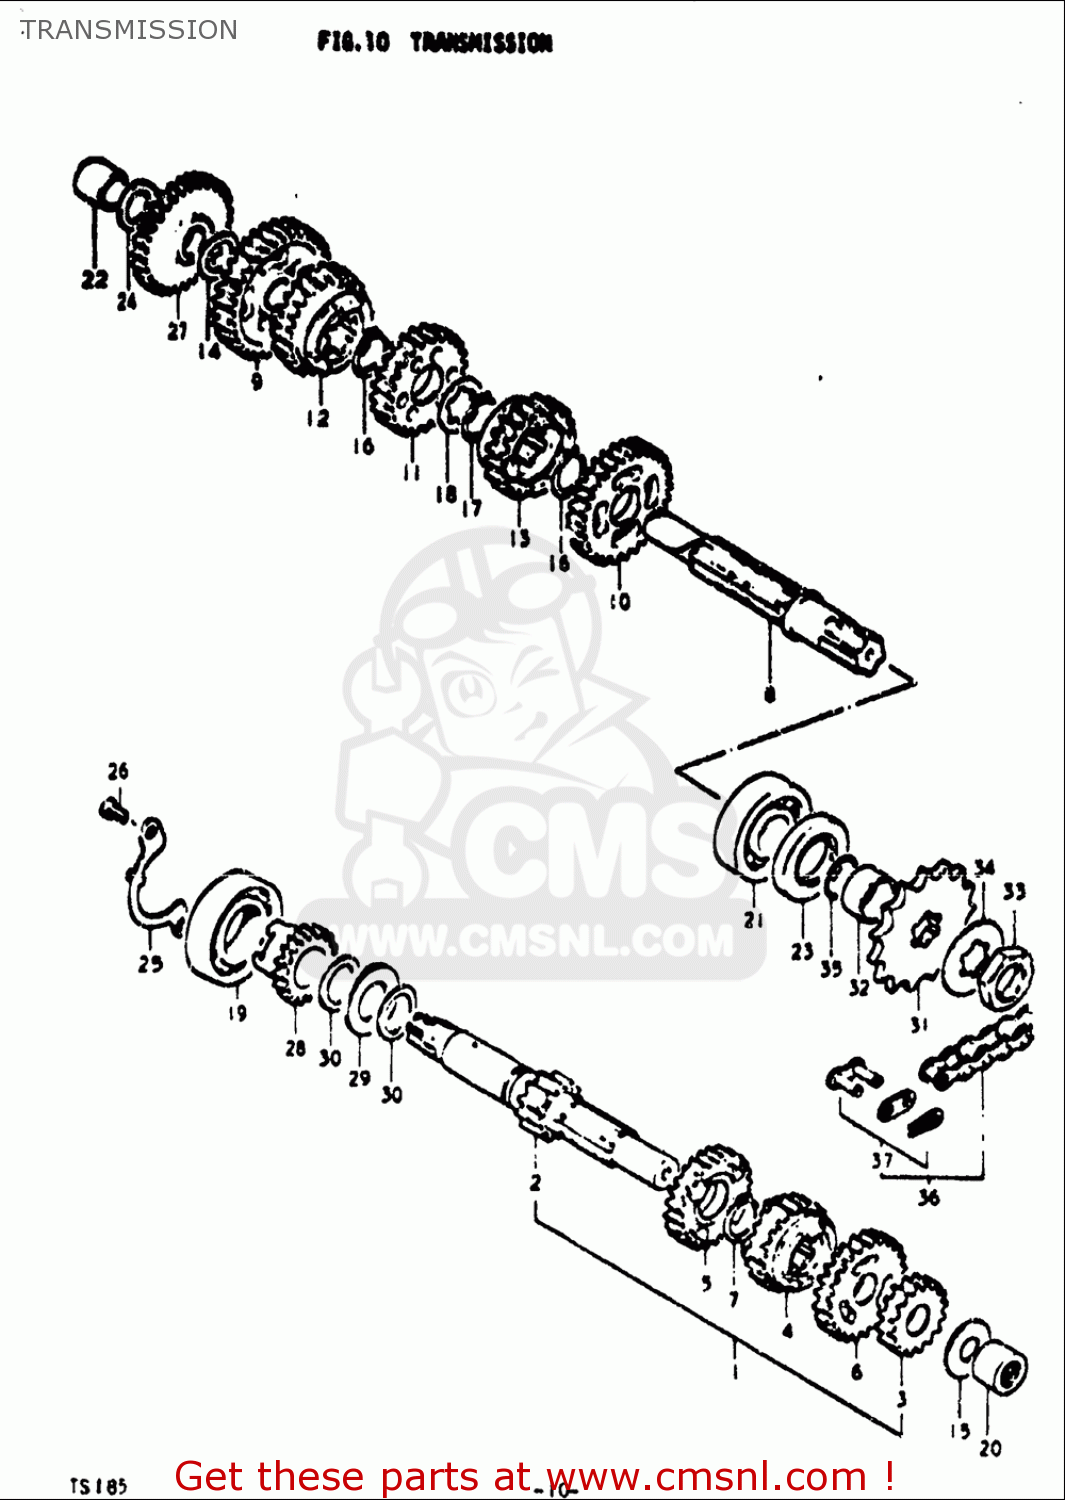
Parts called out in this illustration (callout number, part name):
3	GEAR,2ND DRIVE
4	GEAR,THIRD DRIVE
5	GEAR,4TH DRIVE
7	CIRCLIP
8	SHAFT,DRIVE
9	GEAR,1ST DRIVEN
10	GEAR,2ND DRIVEN
11	GEAR,3RD DRIVEN
12	GEAR,4TH DRIVEN
13	GEAR,5TH DRIVEN
14	SHIM, 15X24X1.0
15	WASHER
16	CIRCLIP
17	CIRCLIP
18	WASHER,LOCK
19	BEARING
20	BEARING(15X22X15)
21	BEARING
23	OIL SEAL (25X44X7)
24	WASHER
25	RETAINER,CNTR SHAFT BEARING
26	SCREW
28	GEAR,KICK STARTER IDLE
29	BEARING(21X32X2.85)
30	WASHER(21X30X0.8)
31	SPROCKET,ENGINE
32	SPACER(20X25X12.5)
33	NUT
34	WASHER,LOCK
35	O RING(D:1,ID:19.5)
36	CHAIN ASSEMBLY,DRIVE
37	JOINT
